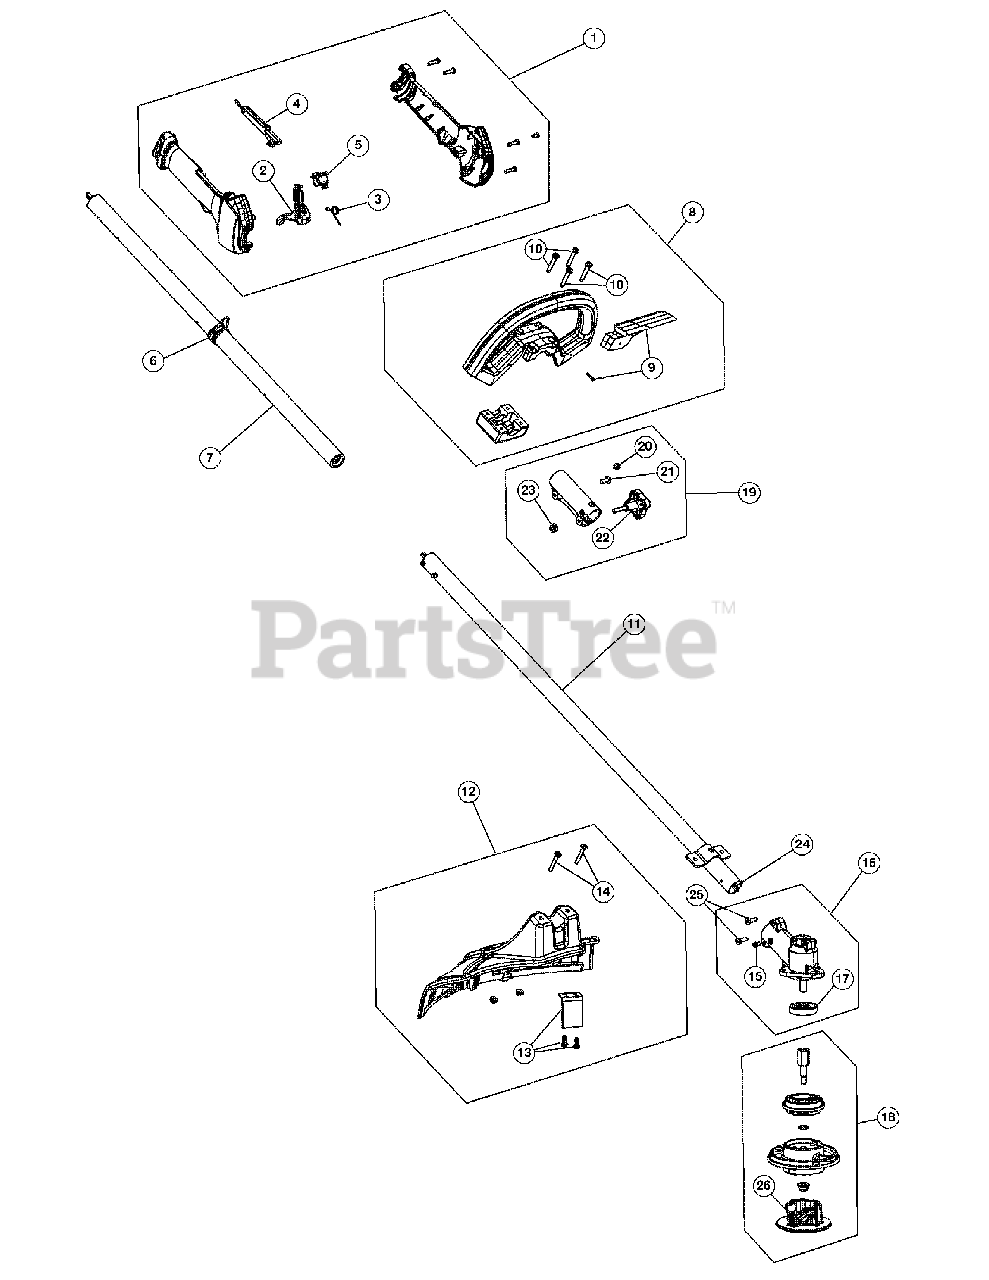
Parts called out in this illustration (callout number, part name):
1	Throttle Housing Assembly (Incl Ref No. 2-5)
2	Throttle Trigger
3	Spring
4	Throttle Lock-out
6	Shoulder Strap Clip
7	Upper Drive Shaft Housing Assembly
8	D-Handle Assembly (Incl Ref No. 9 & 10)
9	Barrier Bar Assembly
11	Lower Drive Shaft Housing Assembly
12	Shield Assembly (Incl Ref No. 13 & 14)
13	Blade Assembly
15	Anti-Rotation Screw
16	Gear Box (Incl Ref No. 15, 17 & 25)
17	Gear Box Spacer
18	Cutting Head Assembly (Incl Ref No. 26)
19	Split Boom Coupler (Incl Ref No. 20-23)
22	Adjustment Knob
23	Knob Retaining Nut
24	Lower Flexible Drive Shaft
25	Gear Box Screw
26	Cutting Head Cap
